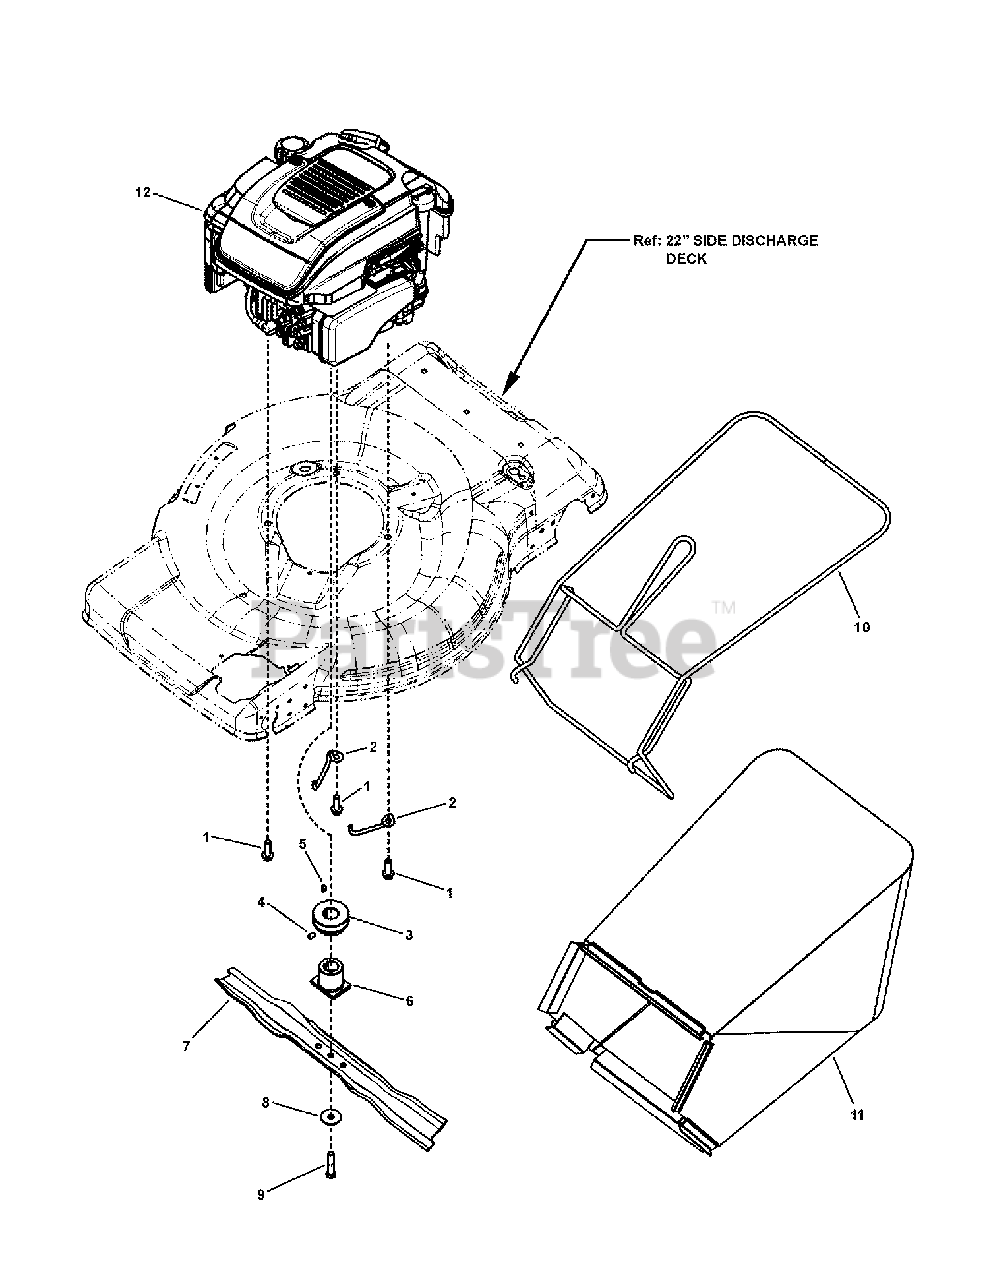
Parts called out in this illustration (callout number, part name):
1	SCREW, 3/8-16 x 1-1/4" Hex Washer Self-Tap
2	BELT GUIDE, Engine, FWD
3	PULLEY, Engine
4	SET SCREW, 5/16-18 x 1/2" Hex Recess
5	KEY, # HP-506 Hi-Pro
6	BLADE HUB
7	BLADE, Wave, Steel Deck
8	WASHER, Cone
9	SCREW, 3/8-24 x 2" Hex Head Cap, GR 5
10	BAG FRAME, Rear Discharge (weldment)
11	GRASS BAG, 22" Rear Discharge
12	* ENGINE, B&S, 700 Ser, X-Spec
